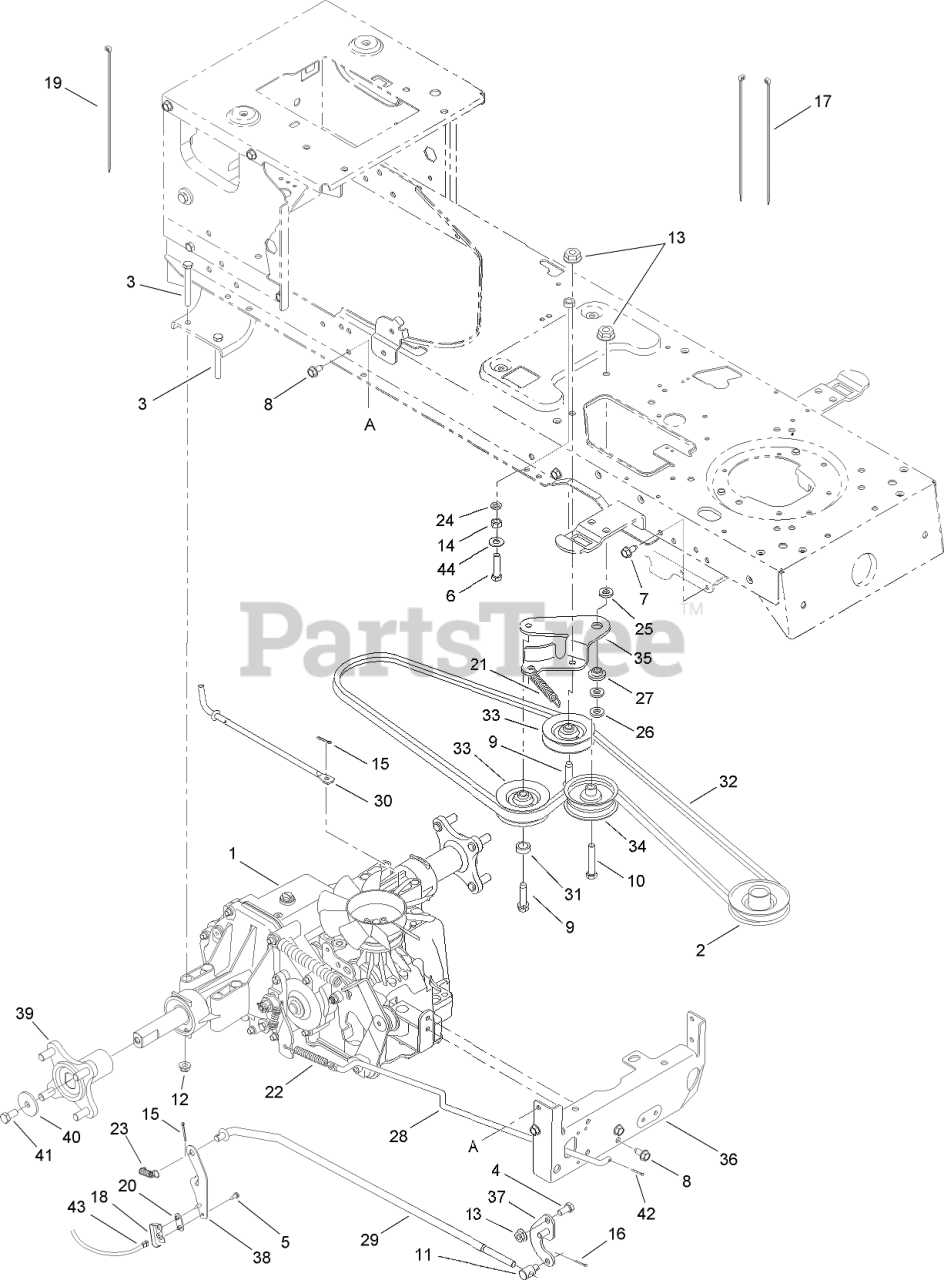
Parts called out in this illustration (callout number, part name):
1	TRANSMISSION ASM
2	PULLEY-ENGINE
3	SCREW-HEX
4	SCREW-HH
5	SCREW-HWHTF
6	SCREW-HH
7	SCREW-HWHTF
8	SCREW-HH, TAP
9	SCREW-TAP
10	SCREW-HH
11	FERRULE
12	NUT-LOCK, FLANGE
13	NUT-LOCK, FLANGE
14	NUT-HEX
15	PIN-COTTER
16	PIN-COTTER
17	TIE-CABLE
18	SWITCH-SPRING, SHORT
19	TIE-CABLE
20	PLATE-INSULATOR
21	SPRING-EXTENSION
22	SPRING-EXTENSION
23	SPRING-EXTENSION
24	WASHER-LOCK
25	WASHER-FLAT
26	WASHER-FLAT
27	SPACER-SHOULDER
28	ROD-BRAKE
29	ROD-CONTROL
30	ROD-DISENGAGE, HYDRO
31	SPACER
33	PULLEY-IDLER, V-TYPE
34	PULLEY-IDLER, FLAT
35	BRACKET-IDLER, CENTER DOUBLE
36	BRACKET-TRANSMISSION
37	BRACKET-CONTROL
38	BRACKET-ACTUATOR
39	WHEEL HUB ASM
40	WASHER-FLAT
41	SCREW-HH
42	PIN-COTTER
43	HARNESS ASM
44	WASHER-FLAT
